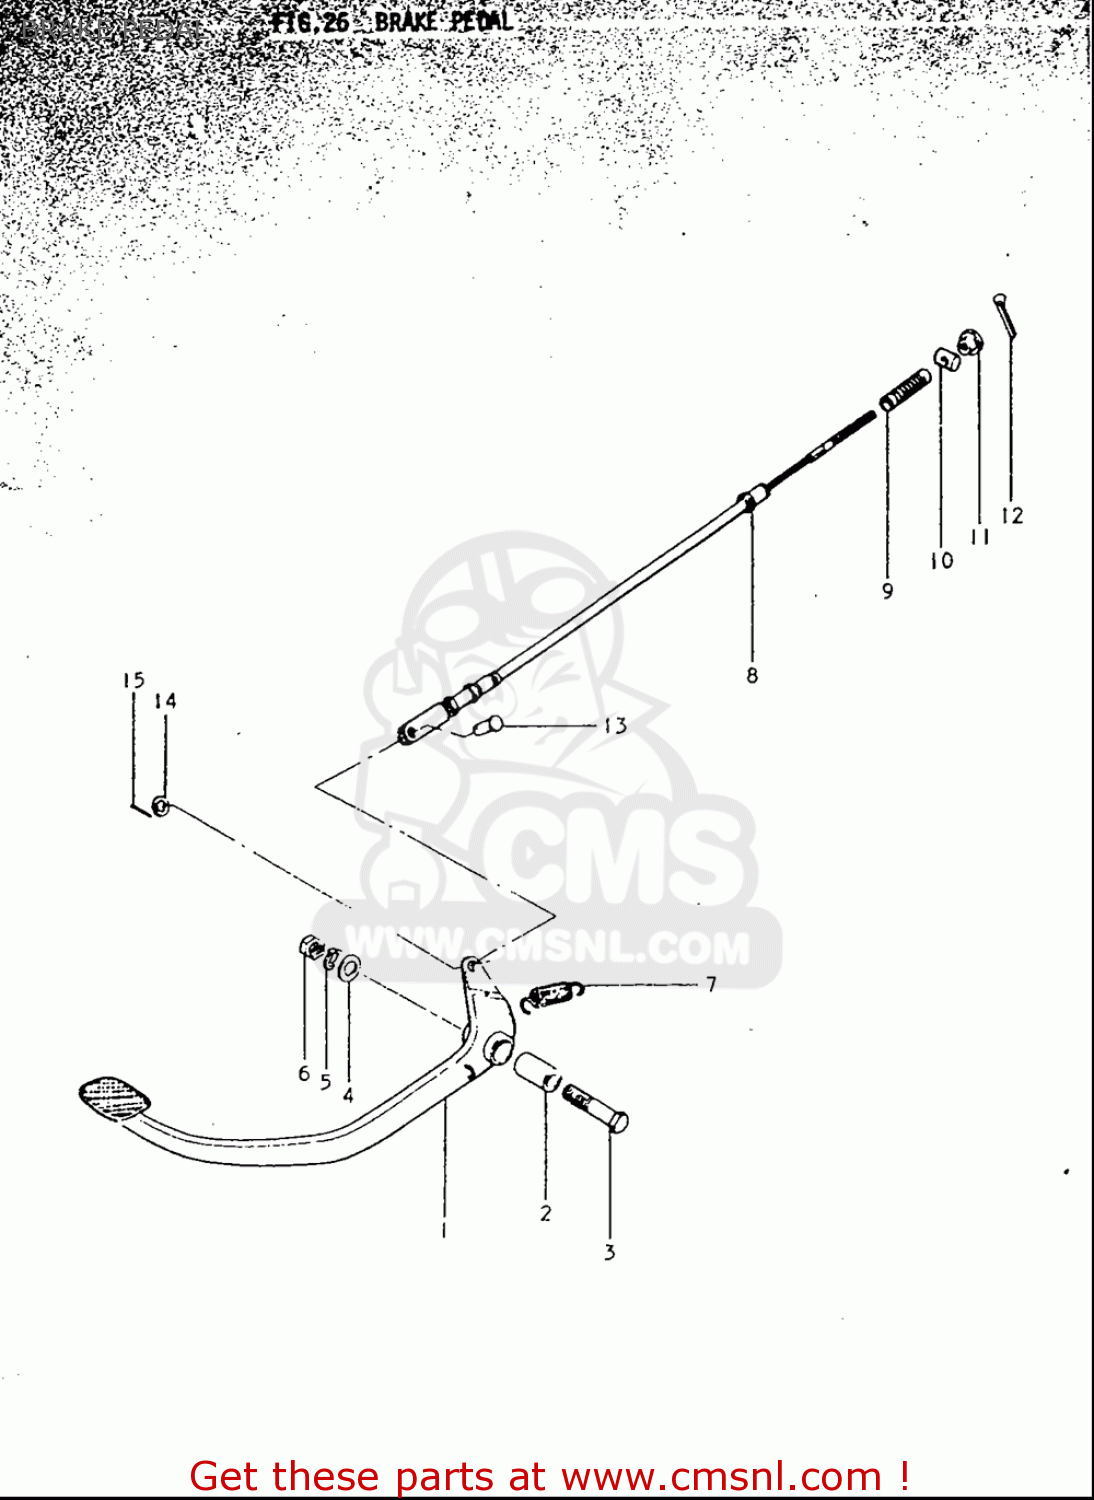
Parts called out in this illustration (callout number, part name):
2	SPACER(10.5X16X30)
4	WASHER
5	WASHER,LOCK
6	NUT
9	SEAL,DUST
10	PIN(13X18)
11	NUT
13	PIN(L:17.5)
14	WASHER
